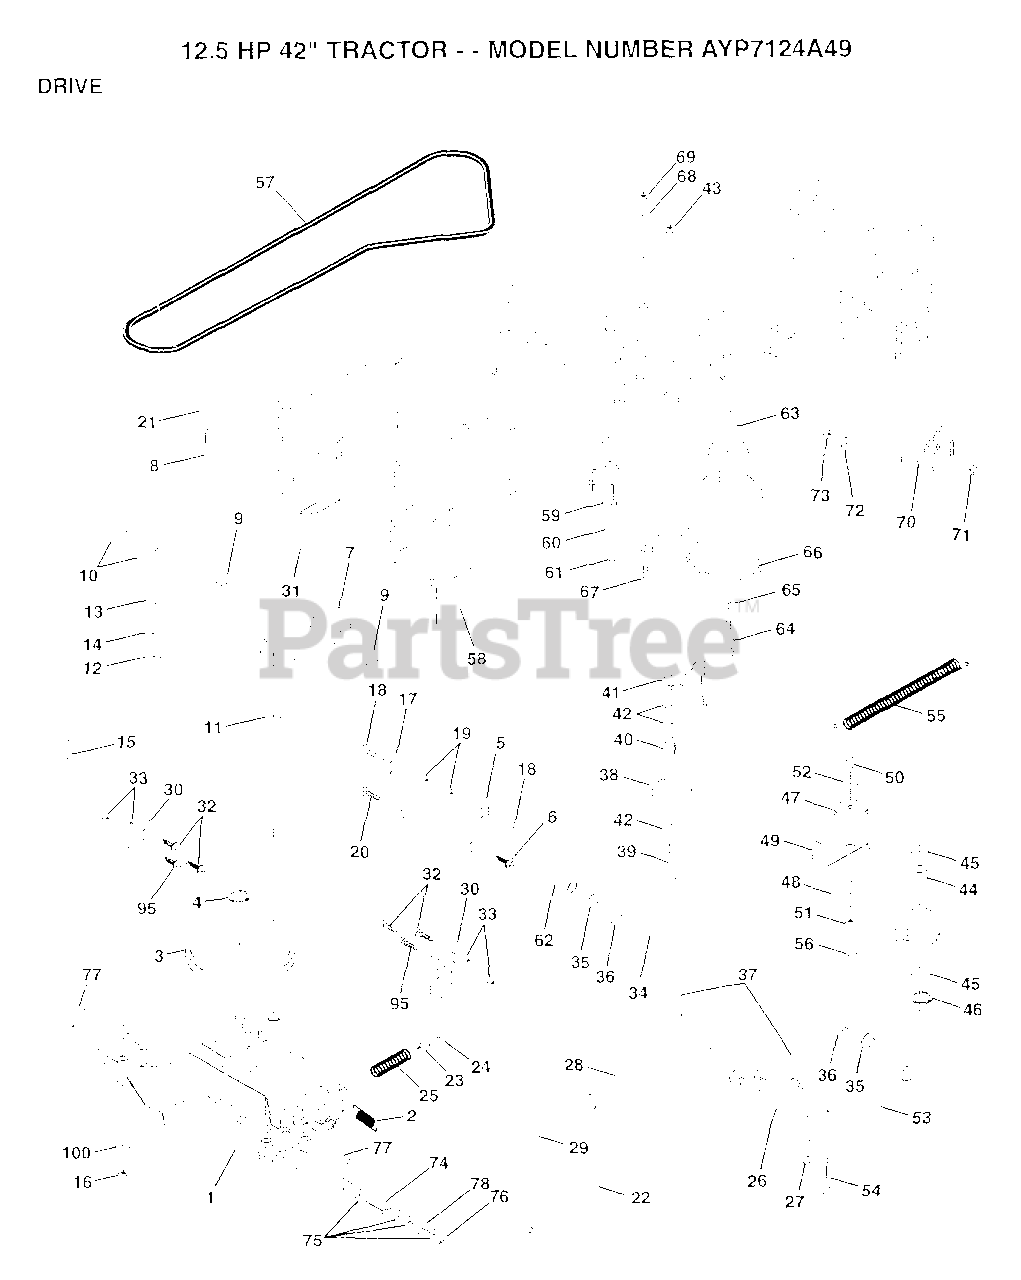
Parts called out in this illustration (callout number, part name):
3	PULLEY TRANS
5	STRAP TORQUE
6	SCREW
8	SHIFT ROD
9	WASHER
10	PIN COTTER 1/8
11	WASH-SHFT PLT LT
12	WASHER LT
14	LOCKWASHER
15	BOLT HEX
17	STRAP TORQUE
20	SCREW
21	KNOB T (1/2-HOLE)
22	BRAKE ROD
23	NUT
24	NUT
25	SPRING ROD LT
26	WASHER
27	COTTER PIN
28	PARKING BRAKE ROD
29	PLUNGER CAP T
30	TRANSAXLE MTG BKT
31	"KEEPER,BELT LH T"
32	BOLT
35	NYLON BEARING
36	WASHER LT
38	PULLEY.IDLER.FLAT
39	BOLT
40	SPACER T
41	BELT KEEPER LT
42	WASHER
44	"LY, BEARING"
45	WASHER LT
46	KLIP RING
48	ARM IDLER
49	RETAIN BELT
52	WASHER
53	"LINK, CLUTCH T"
54	COTTER PIN
55	"SPRING, RETURN LT"
56	COTTER PIN
57	BELT.V.GDRIVE.95
58	"KEEPER,BELT RH T"
59	KEEPER BELT CNTSP
60	WASHER
61	SCREW
62	PEDAL COVER T
63	PULLEY.ENGINE
64	BOLT
65	LOCKWASHER
66	KEEPER.BELT.ENG.L
67	BOLT
68	WASHER
70	KEEPER BELT ENG
71	BOLT
72	WASHER
74	SPACER LT
75	WASHER
76	E-RING LT
77	SQUARE KEY
78	WASHER
100	WASHER M
